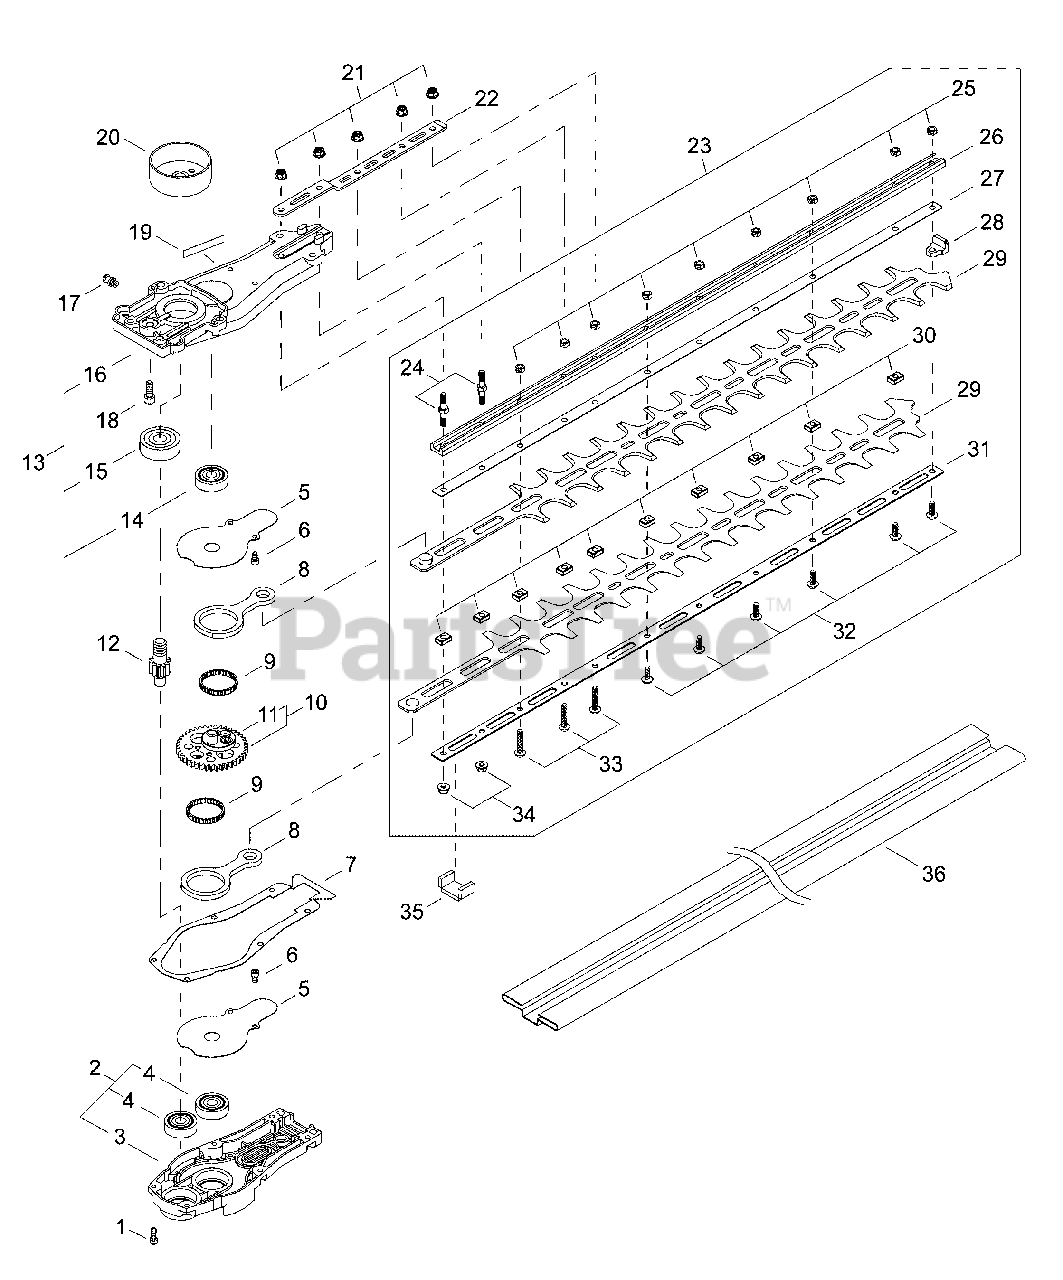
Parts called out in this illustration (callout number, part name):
1	SCREW - 4X14
2	GEAR CASE COVER ASSY
3	CASE, GEAR - LOWER
4	BEARING, BALL - 6200ZZ
5	PLATE, GEAR CASE
6	SCREW - 4X8
7	GASKET, GEAR CASE
8	ROD, CONNECTING
9	BEARING, NEEDLE - 30
10	CAM GEAR ASSY
11	GEAR - SPUR
12	GEAR - PINION
13	GEAR CASE ASSY
14	BEARING, BALL - 6301DDU
15	BEARING, BALL - 6200ZZ
16	CASE, GEAR
17	FITTING, GREASE
18	SCREW - 6X16
19	LABEL - LUBRICATION
20	DRUM, CLUTCH
21	NUT - 5
22	PLATE, ANGLE
23	BLADE KIT - 24" (60cm)
24	STUD - 5
25	LOCKNUT - 5
26	SUPPORT, BLADE - 24" (60cm)
27	PLATE - UPPER
28	BLOCK
29	BLADE - 24" (60cm)
30	SPACER
31	PLATE - LOWER
32	SCREW - 5X14
33	SCREW - 5X25
34	NUT - 5
35	SEAL, FELT
36	COVER, BLADE - 24" (60cm)
